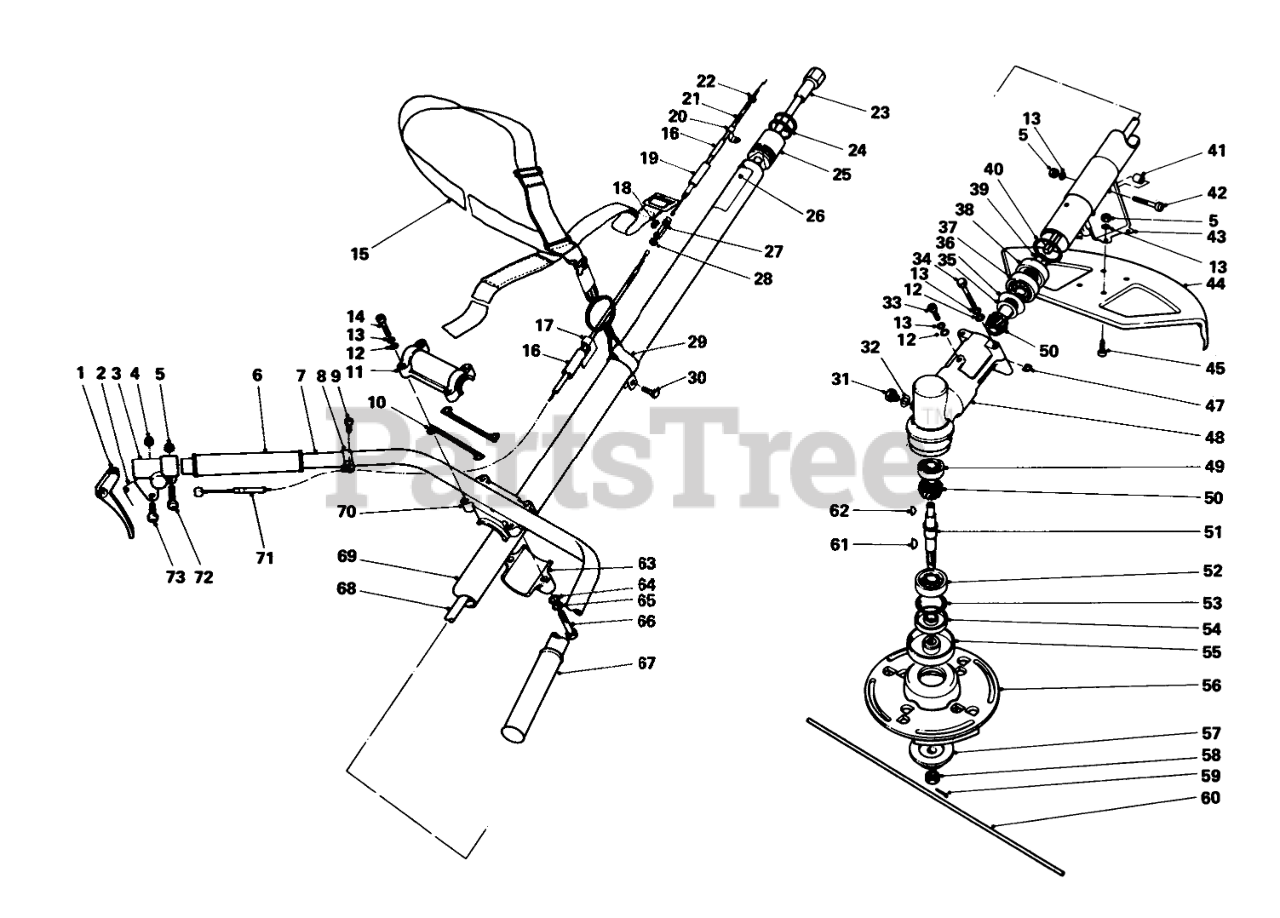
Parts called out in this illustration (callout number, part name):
1	Throttle Trigger
2	Return Spring
3	Bracket, Throttle Trigger
5	Nut
6	Right Hand Grip
7	U-Handle
9	Screw
10	Spacer
11	Handle Bracket, Upper
12	WASHER
13	Washer
15	Shoulder Belt
16	Sleeve, Throttle Cable
17	Clamp
18	Joint
19	Sleeve, Joint Retainer
20	Clamp
21	Throttle Cable
23	Coupler
24	O-Ring
25	Bushing
26	Decal, Caution
27	Retainer, Joint
29	Swivel Hook
32	Gasket
33	SCREW
35	Washer
36	Washer
37	Ball Bearing
38	Ball Bearing
39	Circlip
40	Circlip
41	Spacer
42	Screw
43	Bracket-Head Guard
44	Shield
45	SCREW
47	Spacer
48	Gear Housing
49	Ball Bearing
50	Gear Set
51	Shaft-PTO
52	Ball Bearing
53	Circlip
54	Oilseal
55	Plate-Blade Fixing
56	Cutter Head
57	Plate-Blade Fixing
59	Split Pin
60	Cotter Pin
61	Woodruff Key
62	Woodruff Key
63	Handle Bracket, Lower
64	Washer
65	Washer
67	LH GRIP
68	Drive Shaft
69	Housing, Driving Shaft
70	Body, Handle Bracket
71	Throttle Cable
72	Screw
73	Screw
